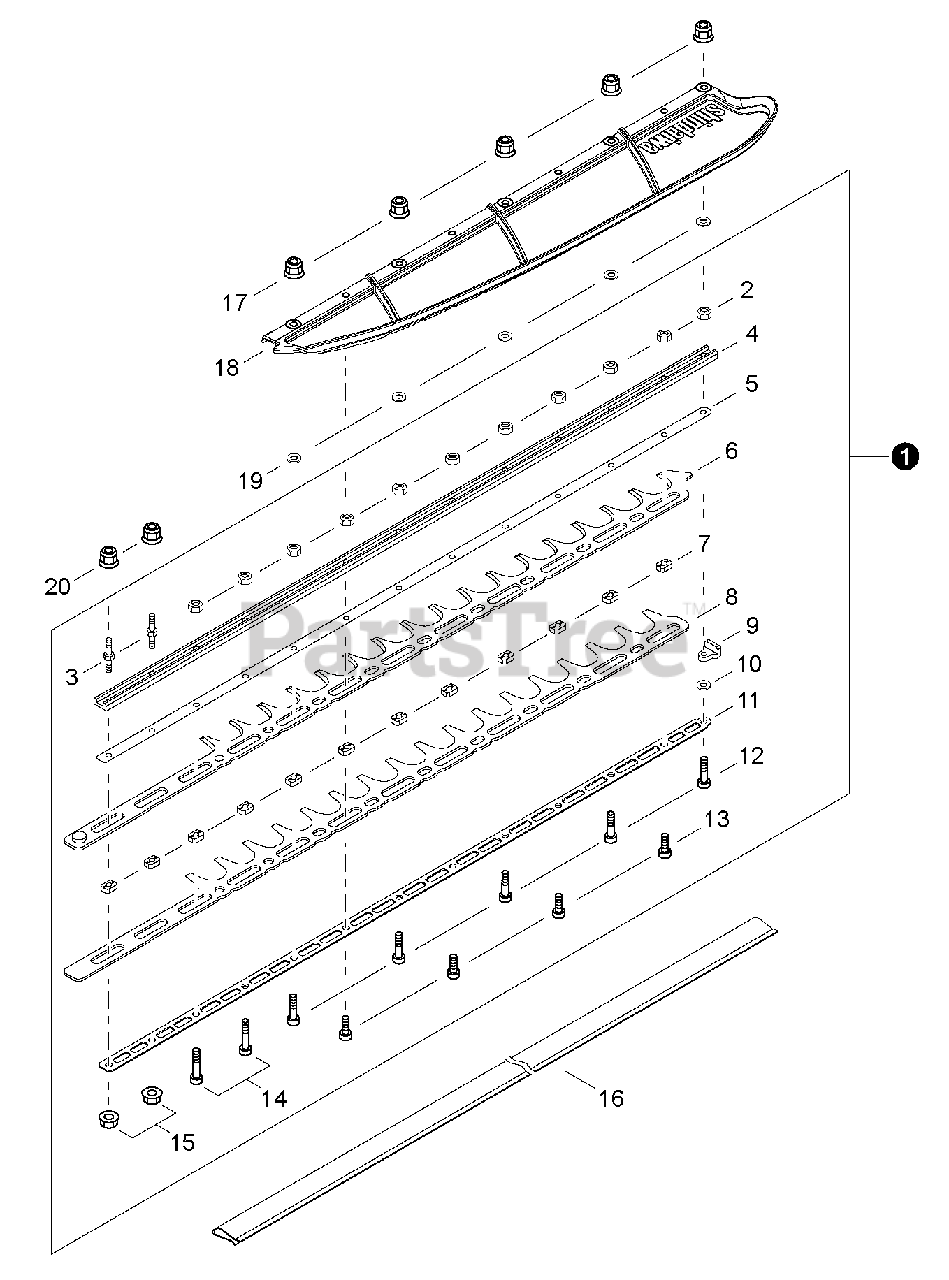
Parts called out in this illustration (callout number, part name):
1	CUTTER ASSY, 40"
3	STUD, MOUNTING M5
4	SUPPORT, BLADE 40"
5	SUPPORT, BLADE 40"
6	CUTTER 40"
8	CUTTER 40"
11	SUPPORT, BLADE 40"
12	BOLT, TORX 5×25
13	BOLT, TORX 5×16
14	BOLT, TORX 5×30
16	SCABBARD
18	DEFLECTOR, DEBRIS
19	WASHER, FLAT 5.5×10×0.8
